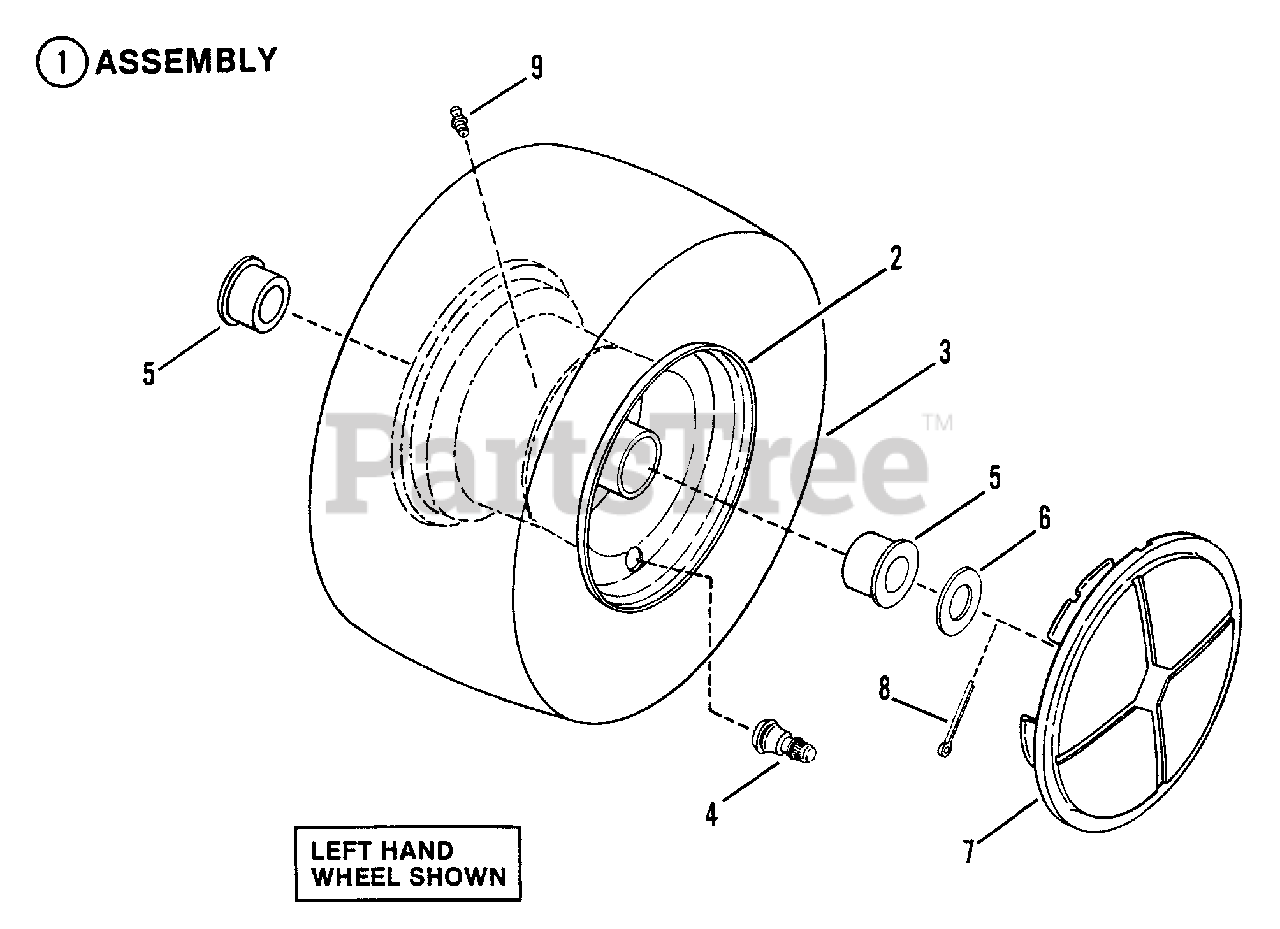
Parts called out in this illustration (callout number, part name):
1	ASSEMBLY, Front Tire & Rim
2	RIM, 6 x 4.50
3	TIRE, 15-6.00 x 6
4	VALVE, Air (Snap-in)
5	BEARING, Wheel
6	WASHER
7	WHEEL-COVER
8	COTTER-PIN
9	FITTING, Lube 1/4-28 Tapered Thread
